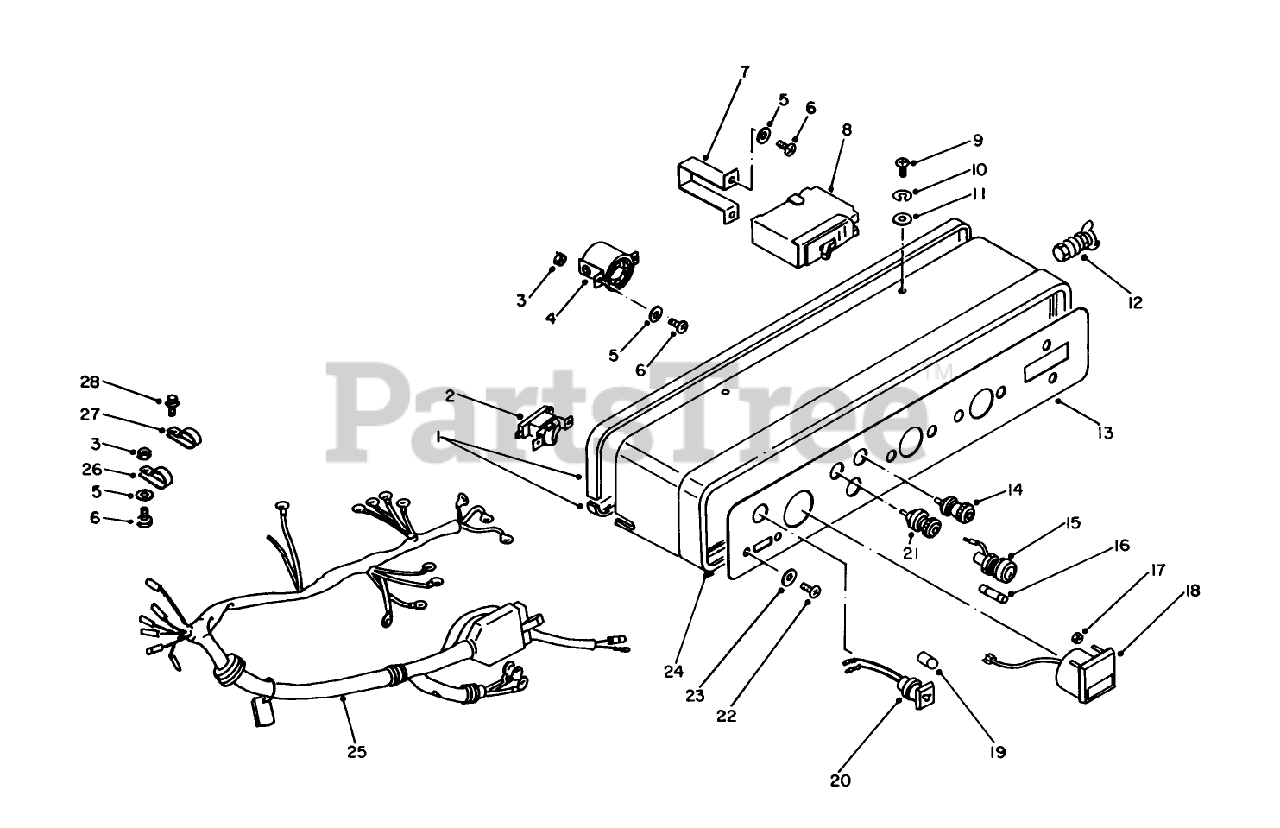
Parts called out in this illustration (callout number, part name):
2	Switch
4	Receptacle
5	Washer
6	Screw
7	BREAKER HOLDER
8	CIRCUIT BREAKER
9	SCREW
10	Washer
11	WASHER
12	GROUND TERMINAL
13	Plate
14	Terminal
15	Fuse Holder (Incl. Ref. #16)
18	Meter-Voltage
20	Lamp (Incl. Ref. #19)
21	TERMINAL (-)
22	SCREW
23	Washer
24	Control panel
25	Wire Harness
26	Clamp
27	Clamp
28	SCREW-HHF
